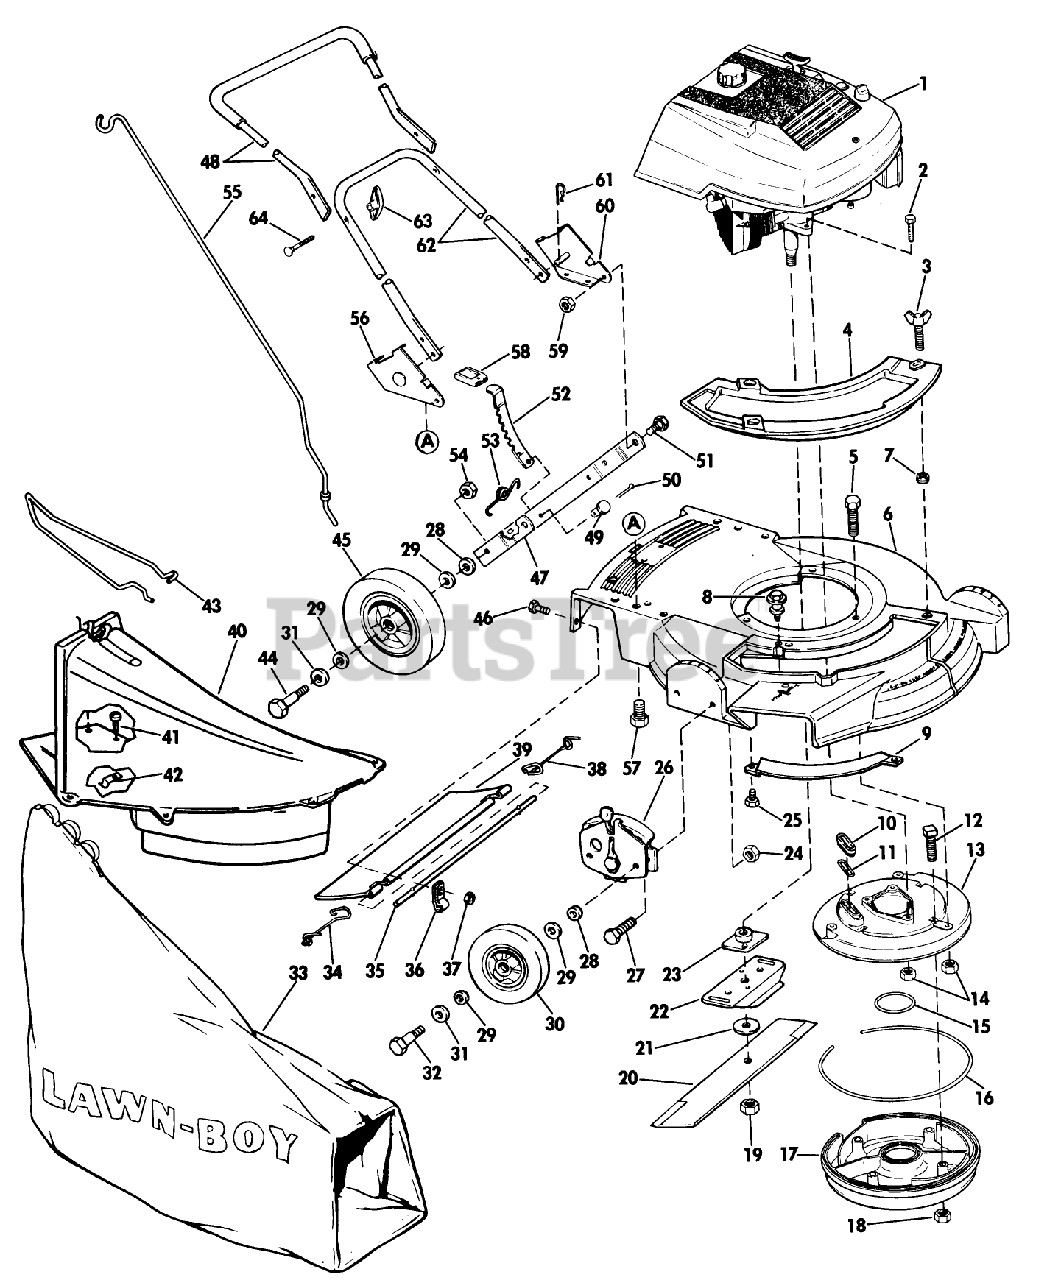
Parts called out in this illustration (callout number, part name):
1	See ENGINE, STARTER, MAGNETO CARBURETOR: MODELS USED ON: 5242, 5272, 7224 AND 7263 for Parts List
3	WING SCREW LAWRE
5	SCREW V
9	TOE BAR 19"
9	BAR-TOE
11	GASKET S
14	NUT-LOCK F
16	Gasket Muffler (outside)
18	LOCKNUT E
19	NUT-BLADE
21	WASHER
23	PLATE AND COLLAR ASM
28	WASHER WROUGHT
32	BOLT WHEEL
33	ORD LB 89802 WHOLE GOODS
34	SPRING;TRAILING SHIELD RH
35	ROD T/SHIELD ADV WIRE
35	ROD 21" ADVANCE
36	CLAMP ROD KMC
38	SPRIG T/SHLD ASOC
51	BOLT-SHOULDER
53	SPRING N.A.S
54	LOCKNUT
55	ROD GRASSBAG
57	SCREW
61	HAIR PIN
63	NUT-WING
